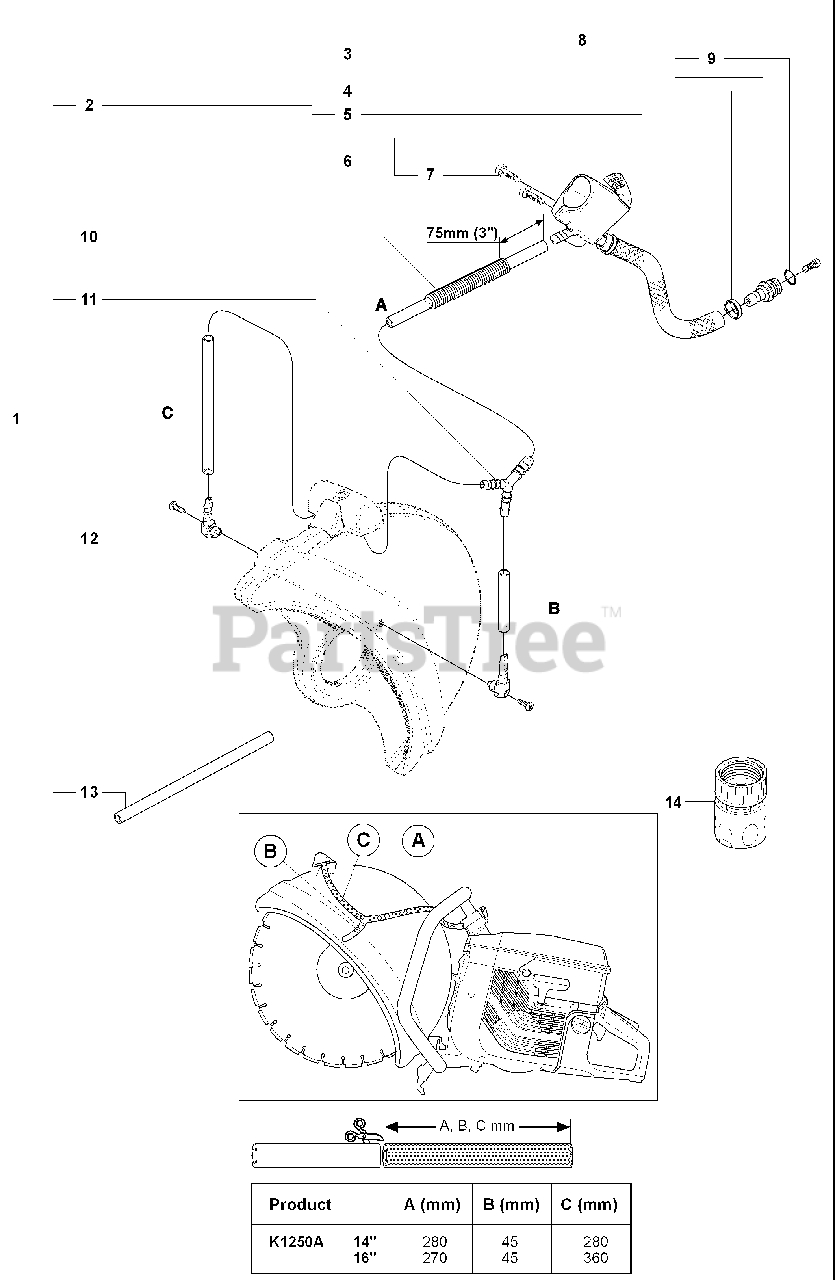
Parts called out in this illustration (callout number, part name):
1	WATER HOSE KIT
2	HOSE
3	NIPPLE
4	HOSE CLAMP
5	HOSE
6	VALVE ASSY
9	O-RING
10	PROTECTIVE SPRING
13	HOSE
14	COUPLER
